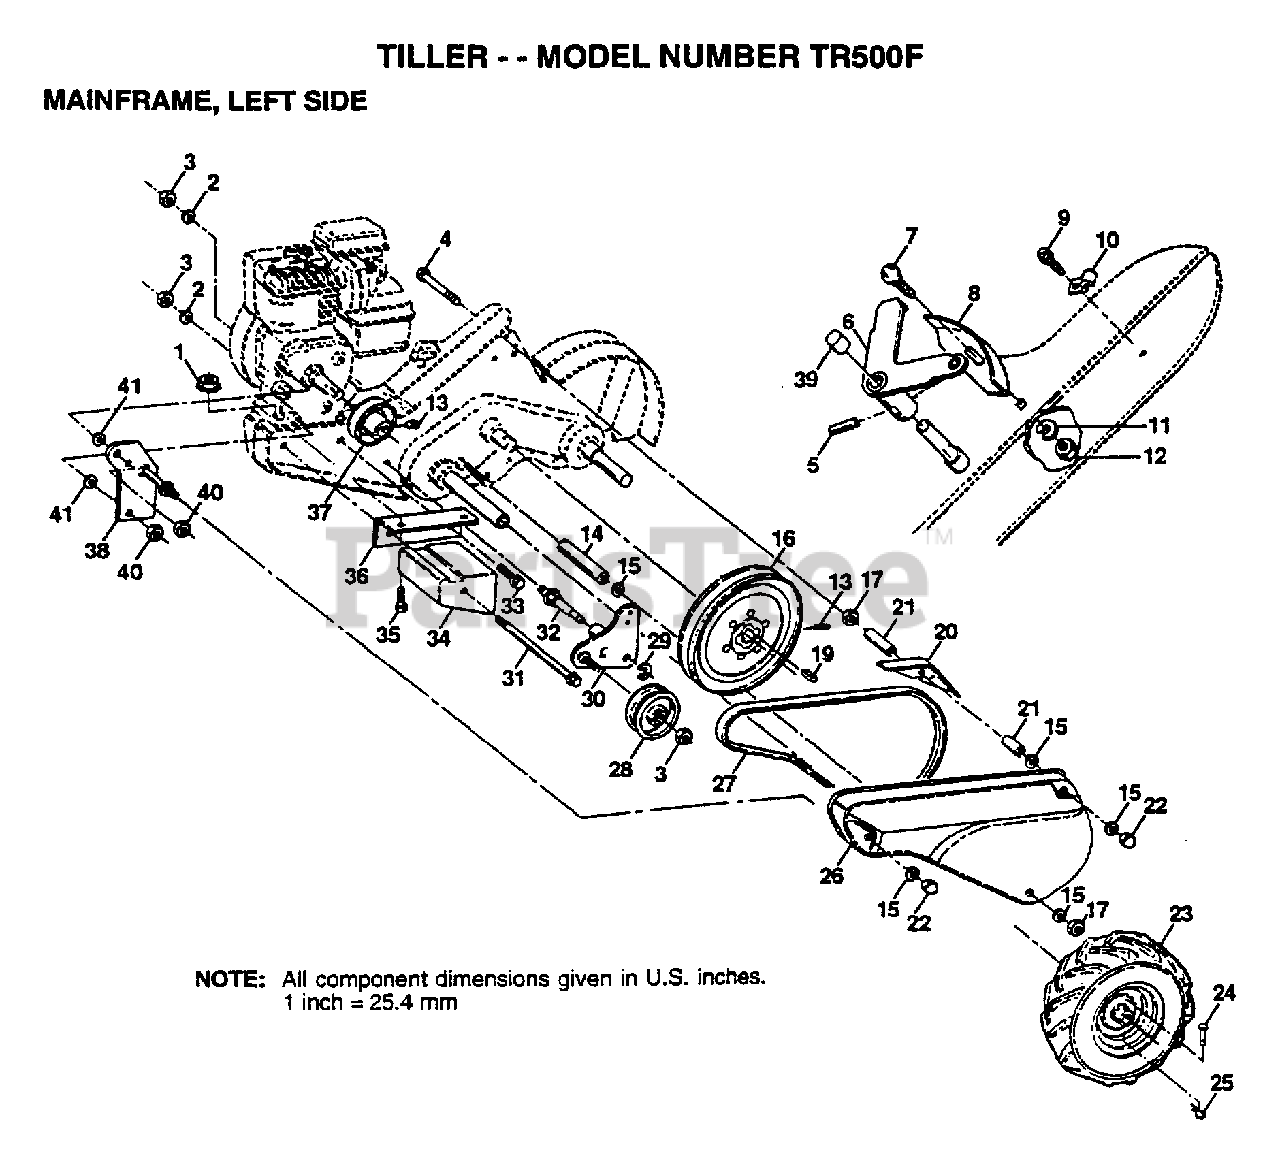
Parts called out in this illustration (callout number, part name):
2	LOCKWASHER
3	NUT.HEX.3/8-16UNC
4	BOLT TI
6	LEVER ASM CRT
7	BOLT
8	PANEL TI
10	CONDIUT CLIP T
11	LOCKWASHER
13	SET SCREW
14	SPACER
15	WASHER
16	"SHEAVE 10"" CRT"
17	NUT.HEX.5/16-18
18	SPACER CRT
19	KEY T
20	GUARD CRT
21	SPLIT SPACER
22	NUT TI
23	TIRE.CHV.13X5.0-6
24	RIVET.DRILL.1.75
25	RETAINER M
26	GUARD.BELT.PNT.
27	BELT-V
28	PULLEY-IDLER TI
29	KLIP RING
31	BOLT CRT
32	SHIFT ARM CRT
33	BOLT
34	COUNTERWEIGHT CRT
35	BOLT.HEX.5/16-1.5
36	BRACKET LH CRT
37	ENGINE SHEAVE
38	BELT GUARD BRKT
39	CAP PLUNGER BLACK
40	NUT
41	WASHER
